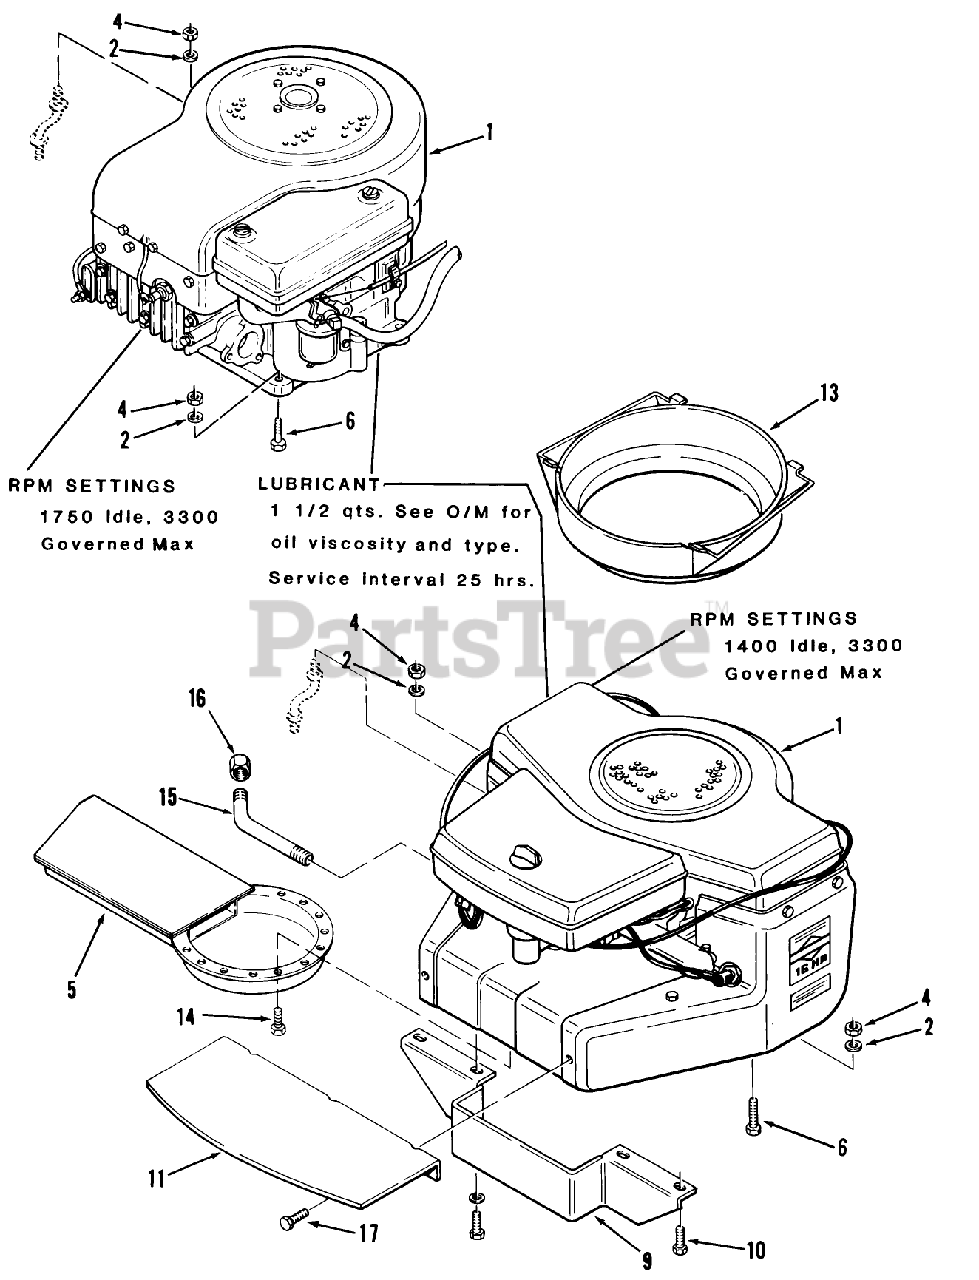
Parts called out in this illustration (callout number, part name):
1	Engine-11HP-BS Model 253707, Type 0131-01-B-115 Only
1	Engine-16HP-BS Model 402707, Type 0130-05 216-5 Only
2	WASHER 5/16 SAE
13	DUCT-AIR INTAKE
